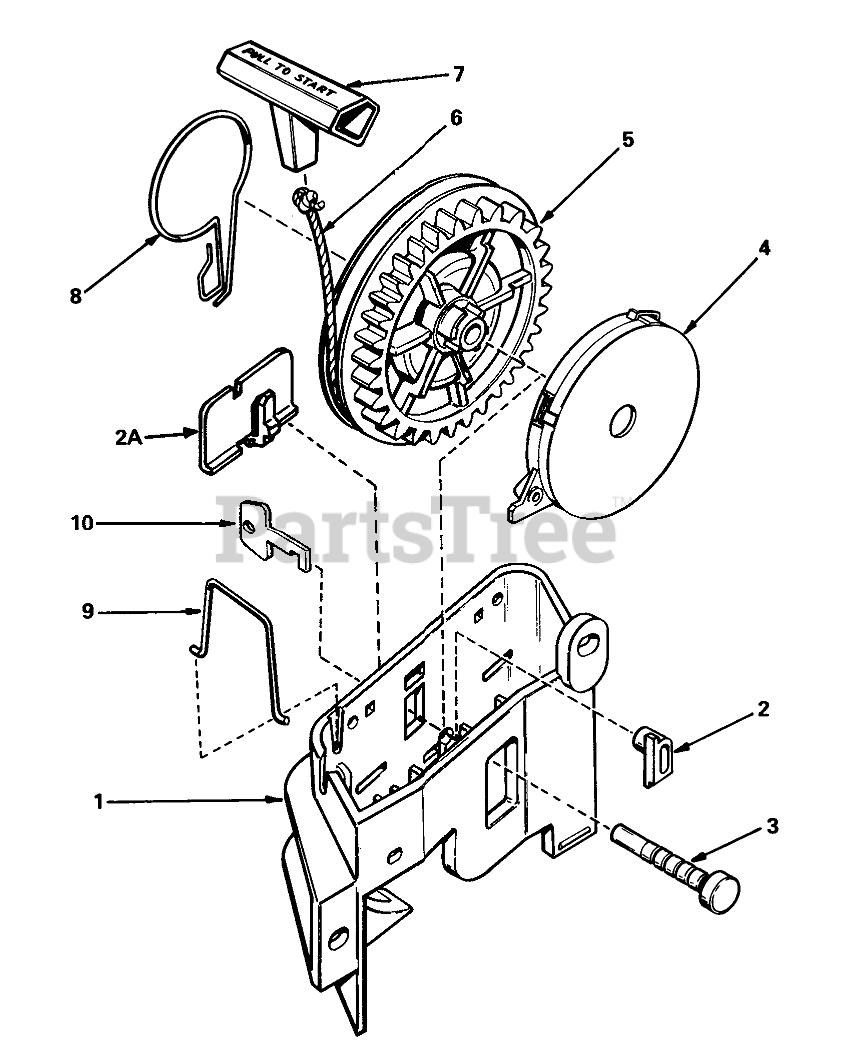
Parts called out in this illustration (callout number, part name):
1	Bracket Starter
2	Pawl, Locking Not used on all engine models)
2A	Clip, Starter Bracket (Used On Starters Not Equipped With Pawl, Ref. No. 2)
3	Pin-Pulley
4	Spring Assy., Rewind (Incl. Ref. #3)
5	Pulley
6	Rope Starter (Length 65" & 9/64" Dia.)
7	Handle-Starter
8	Brake
9	Clip-Rope
10	Key (Not Used On All Engine Models
